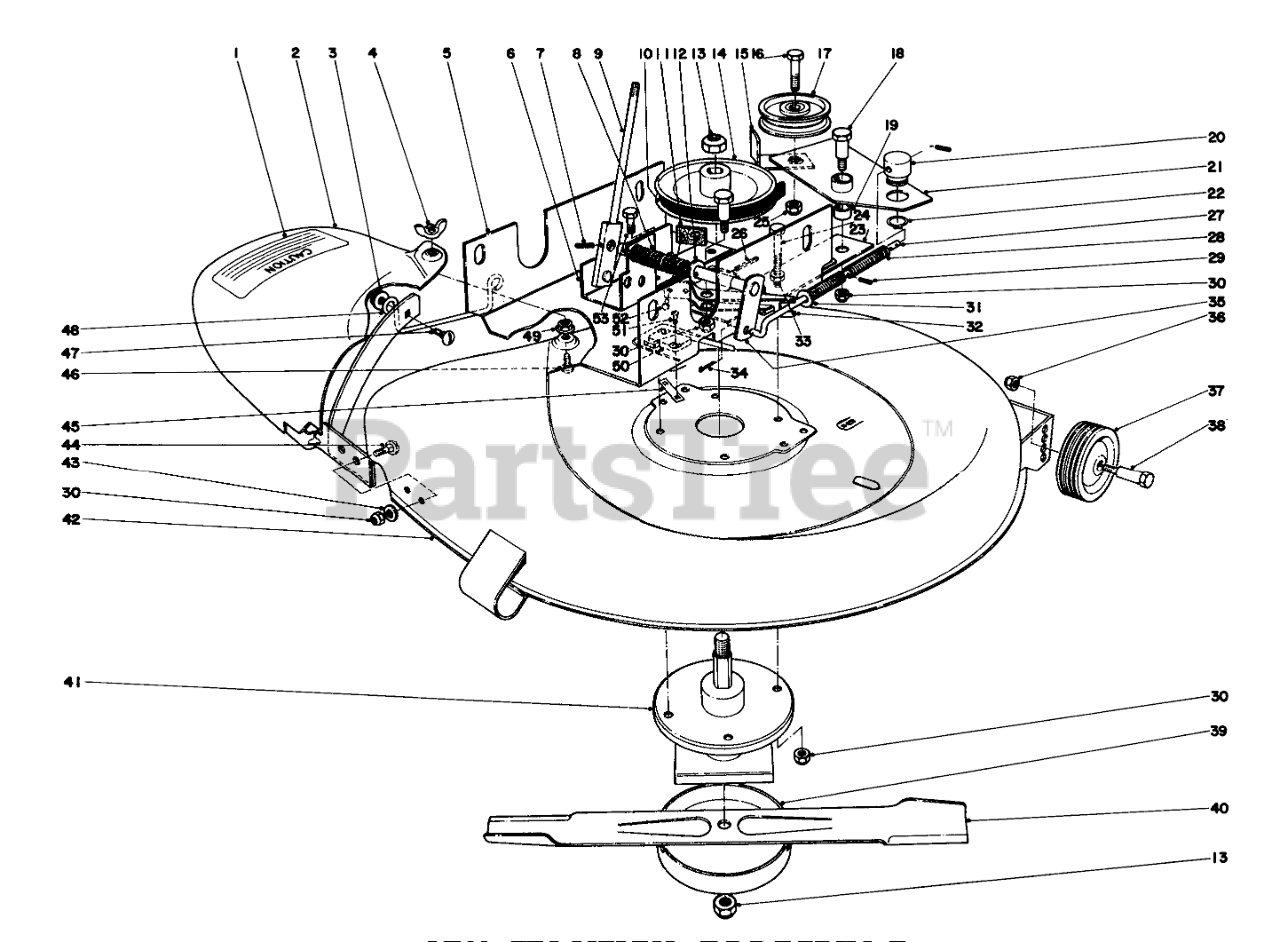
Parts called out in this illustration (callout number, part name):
1	Decal
2	Deflector
3	NUT-LOCK, HHF
4	Wing Nut
5	CHANNEL HT ADJ R
6	Mounting Bracket Blade
7	PIN-SPRING
8	COMP SPRING O
9	Deck Engagement Lever
10	V-Belt
11	Brake Lining-Blade
12	WASHER-FLAT
14	Pulley
15	Belt Retainer
16	SCREW-HH
17	Flat Idler
18	CLUTCH PIVOT BOLT
19	BUSHING
20	Pivot Pin
21	Idler Arm (Incl. Ref. #19)
22	RING-RETAINING
23	Bracket Idler Mounting
24	SCREW-HH
25	NUT-LOCK, CONE
26	Pin-Roll
27	Blade Engage Rod
28	DECK IDLER SPRING
29	PIN-SPRING
30	NUT-LOCK, CONE
31	WASHER
32	Blade Brake
33	NUT-JAM
34	Cotter Pin
35	Linkage
36	Nut
37	Wheel
39	Cup
40	Blade
41	Mower Spindle
42	HOUSING WA R
43	WASHER-FLAT
44	BOLT-CARR
45	NUT-SPEED
46	BOLT-CARR
47	SCREW-CARRIAGE
48	Bracket Foot Guard
49	PAL NUT
50	MICRO SWITCH
51	SCREW-SPH
52	Rivet
53	Screw
